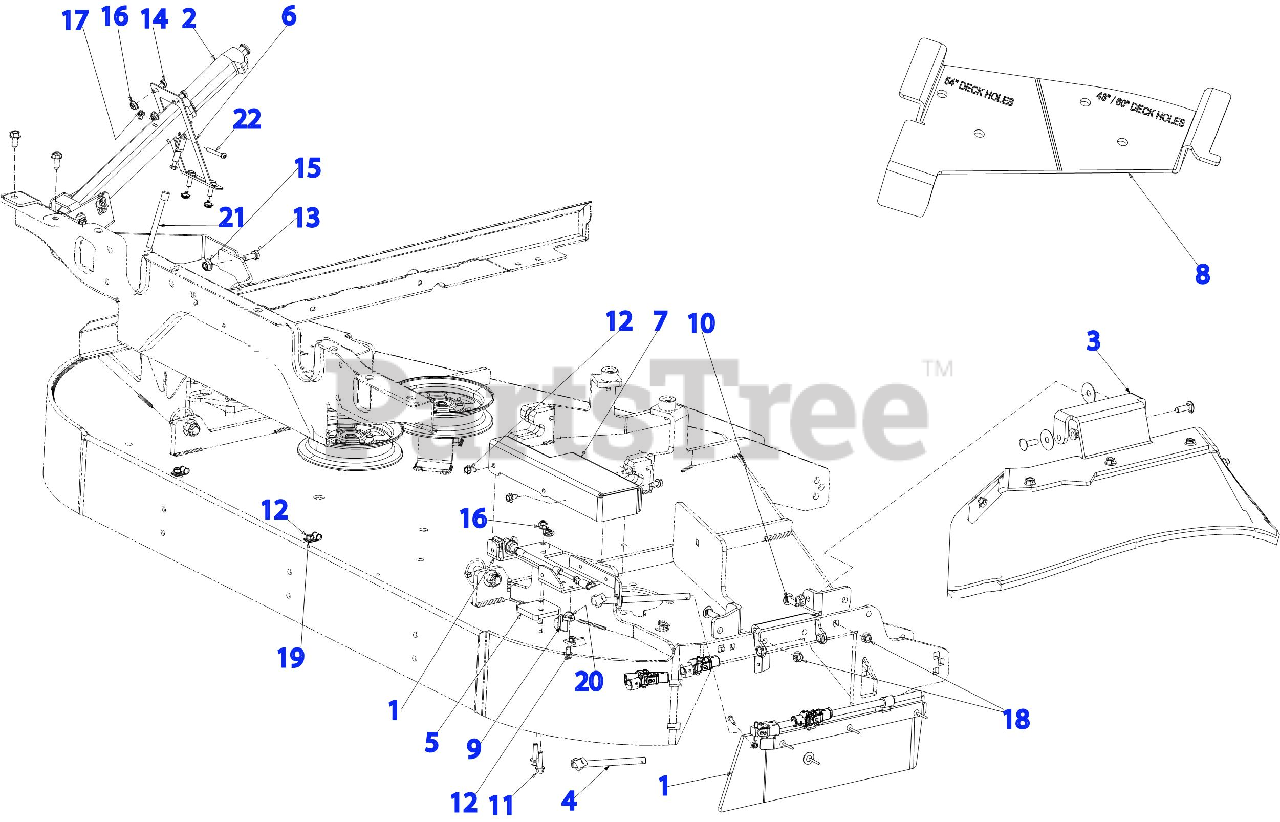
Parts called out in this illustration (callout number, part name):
1	Chute Deck Door Assembly
1	Blade Restrictor Flap
2	Chute Deck Door Handle
3	Chute Assembly
4	Blocker Shaft
5	Cable Bracket Spacer
10	Carriage Screw, 5/16-18 x 1.00
11	Flange Screw, 1/4-20 x 1.0
12	Hex Washer Screw, 1/4-20 x .500
13	Hex Screw, 5/16-18 x .75
14	Hex Screw, 1/4-20 x .75
15	Flange Lock Nut, 5/16-18
16	Flange Lock Nut, 1/4-20
17	Hex Nut, 3/16-24
18	Hex Lock Nut, 5/16-18
19	Battery Clamp, 5/16
20	Rubber Bumper, .62 x .22
21	Control Cable
22	Screw, 10-24 x 1.5
